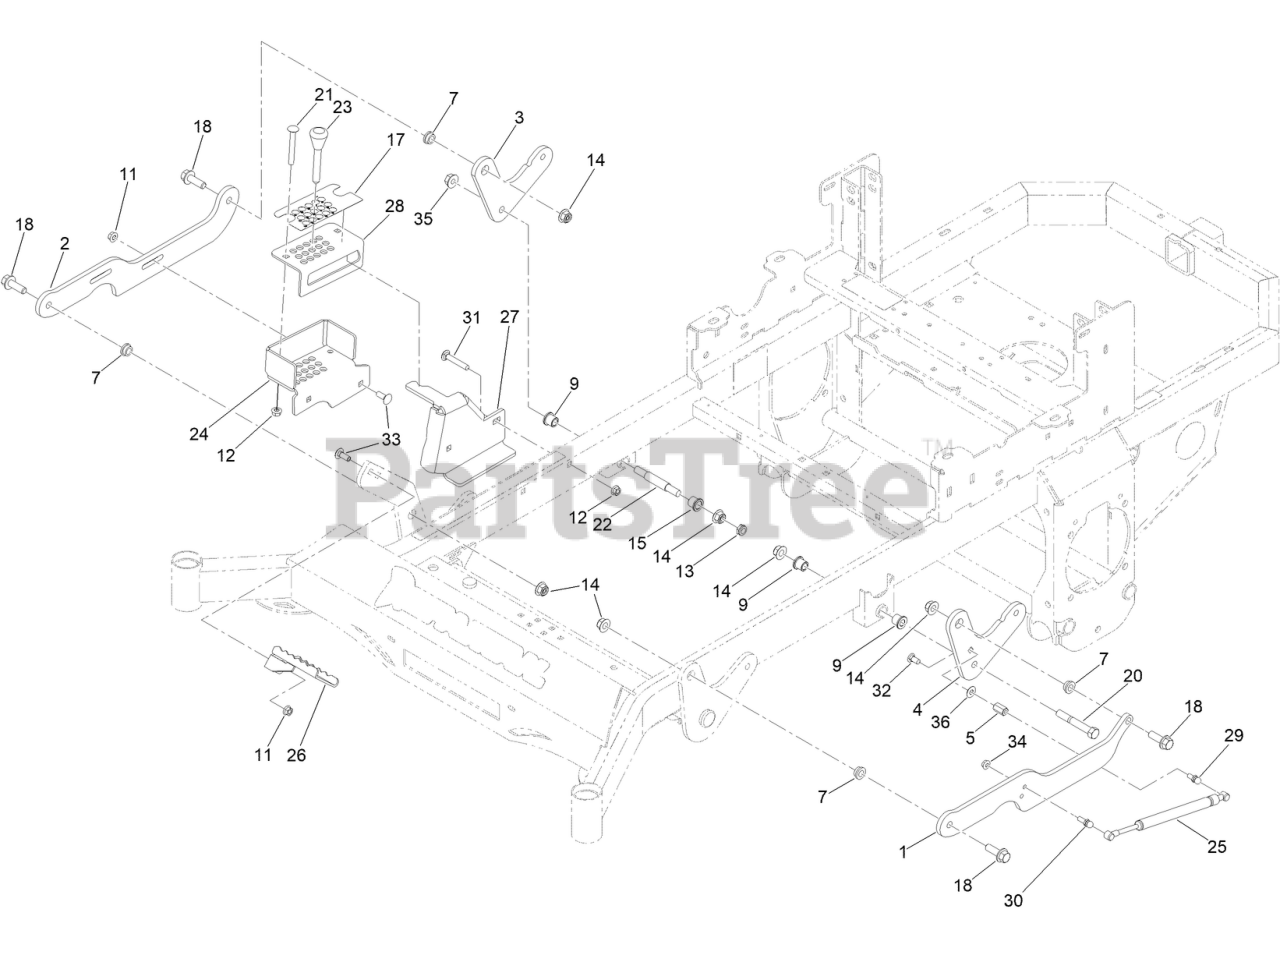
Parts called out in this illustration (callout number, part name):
1	LINK-DECKLIFT
2	2024 DECK HEIGHT ARM RT LINK
3	ARM-DECKLIFT REAR (3/8")
4	ARM-DECKLIFT REAR (3/8")
5	HEX COUPLING NUT - REDUCER (3/8" TO 5/16
7	1/2IN ID X 3/4IN OD X 3/8IN FLANGE BUSH
9	BUSHING-FLANGE
11	3/8-16 HEX FLANGE NUT W/SERR ZINC YELLOW
13	NUT-HEX
14	1/2-13 HEX FLANGE 2-WAY REV CNTR L/NYZ
15	BUSHING-FLANGE
17	DECAL-HEIGHT OF CUT
18	SCREW-HHF
20	1/2-13 X 3-1/2 HEX C/S GR 5 ZINC YELLOW
21	(3/8-16 X 3 CARRIAGE BOLT (GR.5) ZC/YEL)
22	RR DECK HEIGHT BOLT (MACHINED)
23	MAGNETIC PIN FOR STAND ON MWR
24	BRACKET PIN SYSTEM (BOTTOM) PAINTED GREY
25	DECK ASSIST GAS SPRING
26	MWR DECK HEIGHT FOOT PEDAL PAINT
27	2022 DECK LOCK PIN TUBE BRKT
28	2022 DHI PIN ARM LINK TOP BRKT
29	5/16-18X1.286 DAMPER BALL STUD (.562 TL)
30	5/16-18X1.286 DAMPER BALL STUD (.562 TL)
31	SCREW-CARR
32	3/8 X 3/4IN GR 8 CARR BOLT ZINC
33	3/8-16 X 1 CARRIAGE BOLT YZ GR.8
35	NUT-HHF
36	5/16IN USS FLAT WASHER (3/8 ID X 7/8 OD)
